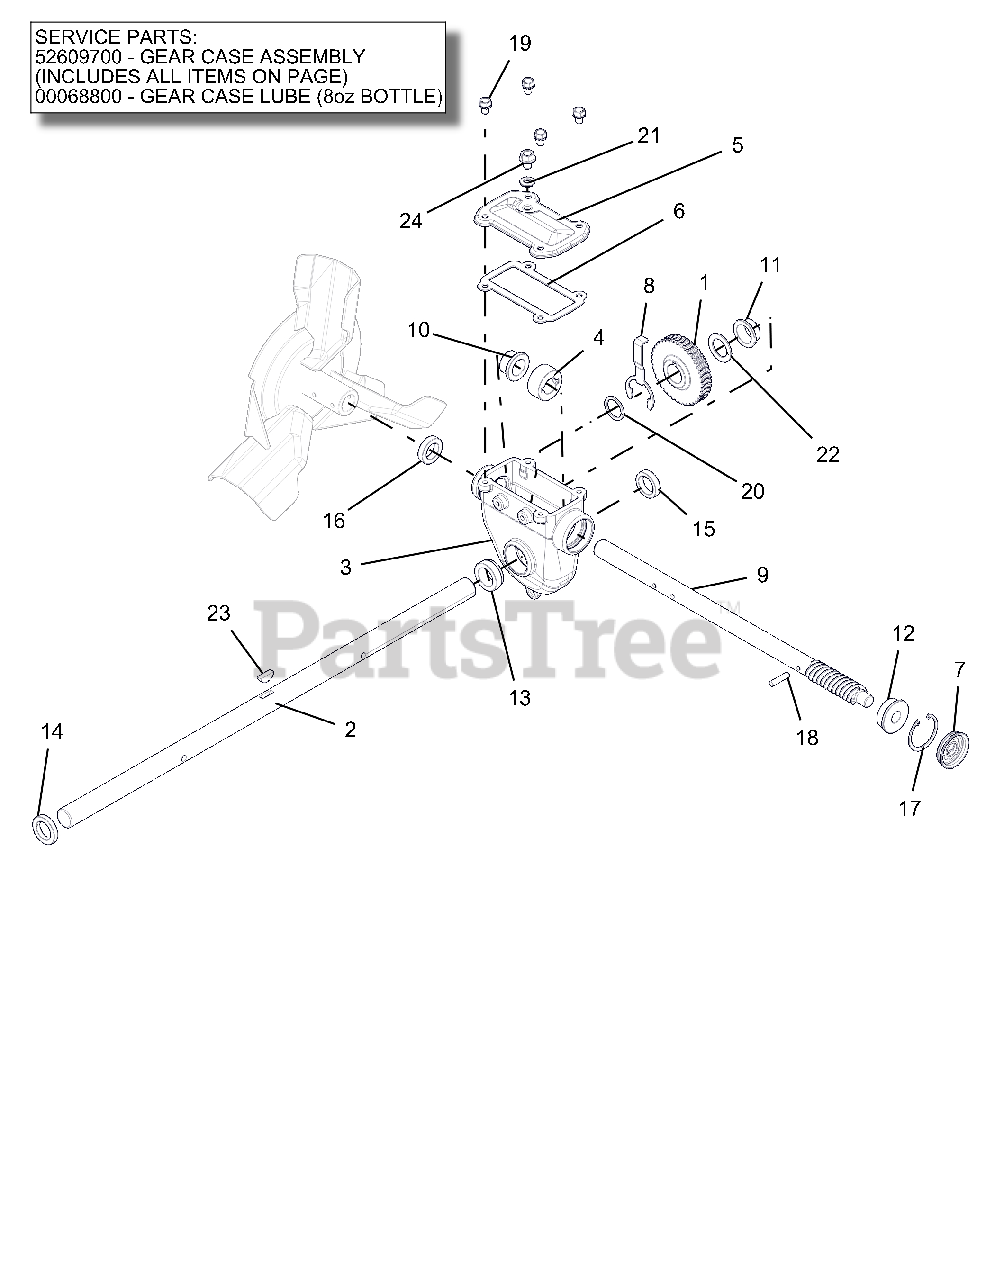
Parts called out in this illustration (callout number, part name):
1	WORM GEAR
2	SHAFT, RAKE-28"
3	GEARCASE, LARGE MACHINED
4	THRUST COLLAR, .875"ID SLIPFIT
5	COVER, TOP - LARGE IRON
6	GASKET, TOP - LARGE GEARCASE
7	COVER, GEAR CASE 1.75"
8	BUSHING RETAINER, LARGE
9	SHAFT, WORM - PRO
10	BSHG-FLG .879X1.128X.75X1.45
11	BSHG-FLG 1.006X1.128X.555X1.45
12	BSHG-FLG .628X1.503X.58X1.725
13	BSHG-FLG LARGE, RIGHT
14	SEAL-OIL .999X1.500X.250 TBC29
15	SEAL-OIL .999X1.375X.312 TBC29
16	SEAL-OIL .873X1.375X.312 TBC29
17	RG-RTNG-INT 1.750X.062
18	PIN-STR .250X1.12 6150
19	BOLT, SEMS .31-18X.50 GR5 YWZC
20	WSHR-FL-STL 1.010X1.250X.068YZ
21	WSHR-BND-SEAL .38X.75X.11 GALV
22	WSHR-FL-STL 1.010X1.505X.062YZ
23	KEY-WDRF .25X.875 HRD #A
24	@SCR-ROLOK .38-16X.50 HWH YWZC
25	GEAR CASE, 28" IRON PRO TOP-LD
26	ARIENS L3 LUBE, 8 OZ BOTTLE
